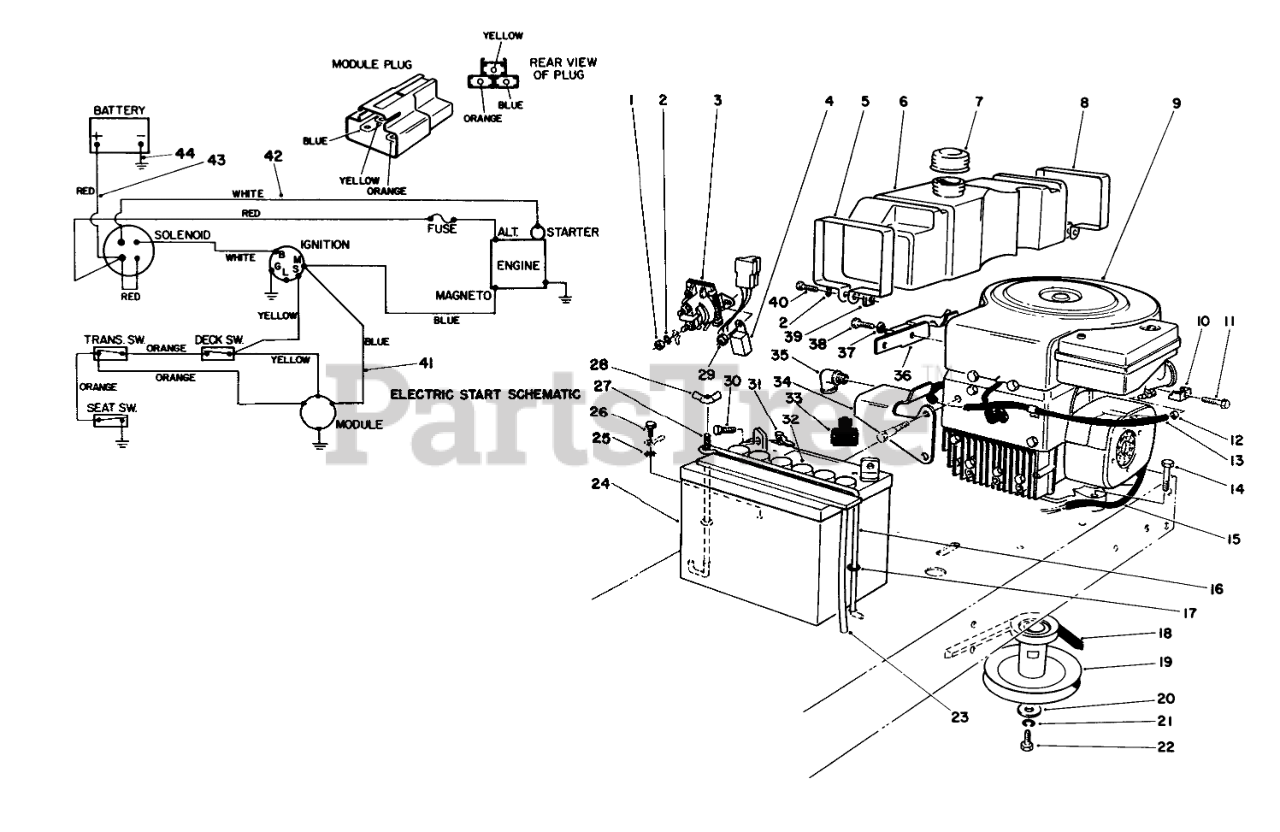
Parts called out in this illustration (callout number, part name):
1	NUT-JAM
2	WASHER-LOCK
3	SOLENOID
4	Module Interlock
5	Retainer-Front
6	TANK-5 QT GAS
7	GAS CAP ASM
8	Retainer-Rear
9	Engine-11 H.P.
10	CLAMP-CASING
11	SCREW W ENGINE
12	FUEL HOSE CLAMP
13	FUEL HOSE
14	SCREW-HH
15	HEAT SHRINK TUBING
16	HOLDDOWN-BATTERY
17	O-RING
18	V-BELT, TRACTION
19	PULLEY
20	WASHER-FLAT
21	WASHER-LOCK
22	SCREW-HH
23	TUBE-BATT DRAIN/80-2600
24	Battery
25	WASHER-LOCK, INTERNAL
26	SCREW-HHF
27	POST-BATTERY
28	NUT-WING
29	NUT-LOCK, CONE
30	SCREW-HH
31	NUT-WING
32	CAP-BATTERY
33	BOOT-TERMINAL
34	BRACKET B
35	ELBOW-STREET, 90 DEG
36	REAR TANK MTG BRKT B
37	WASHER-PLAIN
38	SCREW-HH
39	NUT-SQUARE
40	SCREW-HSH
41	Wire Harness
42	STARTER WIRE HARNESS
43	WIRE ASM
44	WIRE ASM(BATT/GRD.
